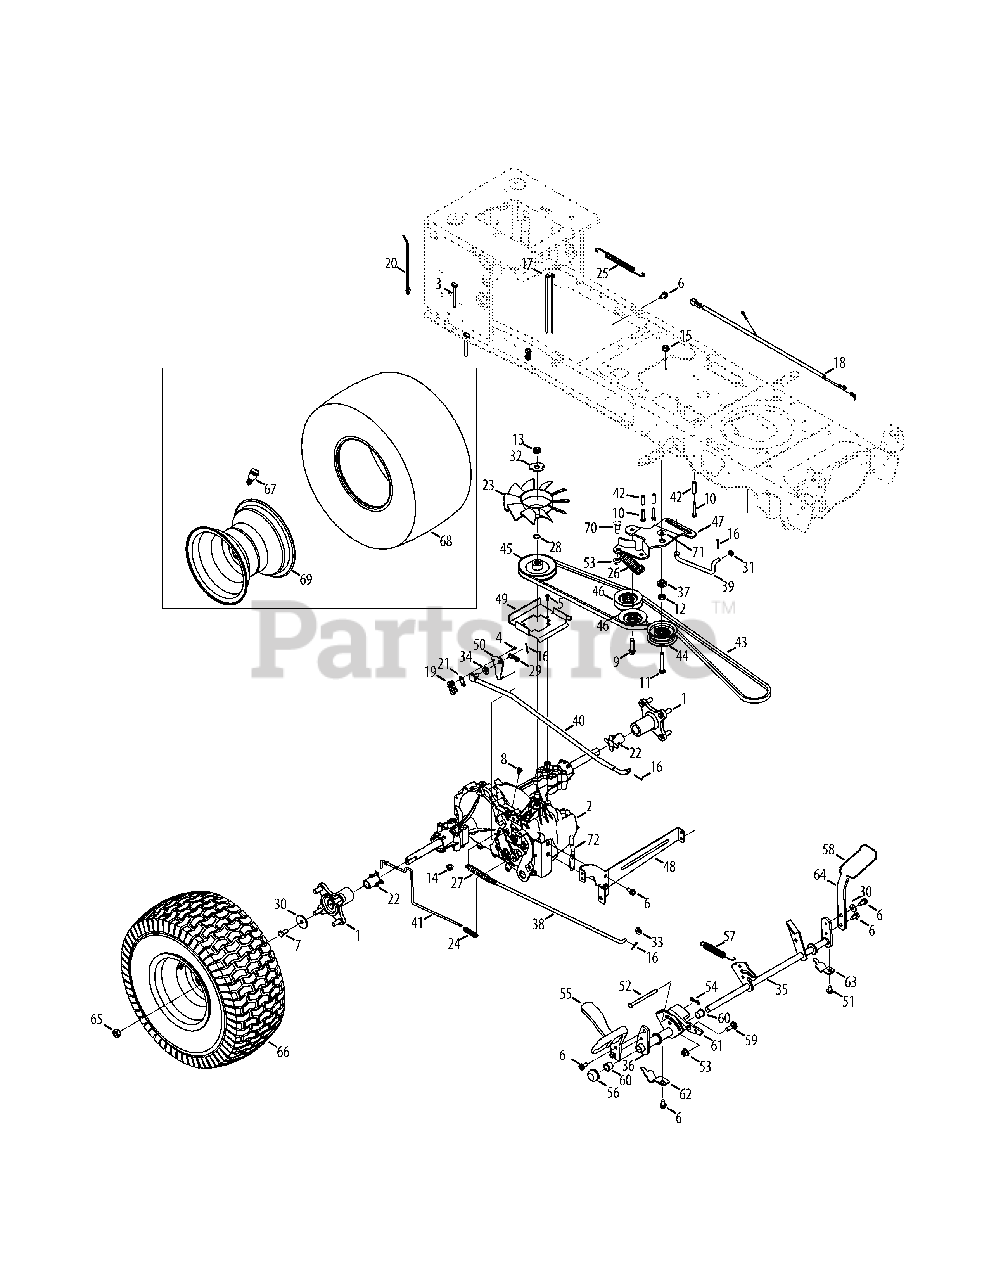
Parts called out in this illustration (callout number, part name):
1	Wheel Hub Assembly
2	Hydro Transmission
3	Hex Head Screw, 5/16-18:2.75
4	Screw, Indented Washer, #8-18:0.500
5	Screw, #10-16:0.500
6	Taptite Screw, 5/16-18:.750
7	Hex Head Screw, 5/16-24:.750
8	Taptite Screw, 1/4-20:0.375
9	Taptite Sems Screw, :3/8-16:1.500
10	Taptite Screw, 1/4-20:1.625
11	Hex Head Screw, 3/8-16:2.25
12	Jam Nut, 7/16-20
13	Jamlock Nut, 1/2-20
14	Flangelock Nut, 5/16-18
15	Flangelock Nut, 3/8-16
16	Cotter Pin, 3/32:1.0
17	Cable Tie. 3/16 x .05 x 7.4
18	Jumper Harness
19	Short Spring Switch
20	Push Mount Cable Tie 7.5 LG
21	Insulator Nut Plate
22	Sleeve, .765 ID x 1.500 LG
24	Extension Spring, .48 OD x 2.03
25	Extension Spring, .500 DIA x 12.6 LG
26	Extension Spring, 1.00 DIA x 4.75
27	Extension Spring, .59 OD x 4.00 LG
28	Wire Ring
29	Extension Spring, .375 OD x 1.44 LG
30	Bell Washer, .340 x .872 x .060
31	Flat Washer, .330 x .630 x .0635
32	Lock Washer
33	Flat Washer, .344 x .750 x .120
34	Flat Washer, .407 x .812 x .135
35	Brake Control Assembly
36	Hydro Pedal Bracket Assembly
37	Shoulder Spacer, 1.375 x .380 x .183
39	Foot pedal Bypass Transmission Rod
40	Hydro Control Rod
41	Hydro Bypass Rod
42	Spacer, 260 x .372 x 1.420 LG
43	V-Belt, 4L x 78.9 POLY
44	Flat Idler Pulley, 2.75 OD
45	Input Pulley, 4.13 DIA
46	V Idler Pulley, x 3.06
47	Center Idler Bracket
48	Hydro Mounting Bracket
49	Belt Disengage Support Bracket
50	Switch Actuator Bracket
51	Taptite Screw, 5/16-18:0.625
52	Clevis Pin, 5/16 x 3.985
53	Flangelock Nut, 3/8-16
54	Bow-Tie Cotter Pin
55	Control Pedal
57	Extension Spring, .63 DIA x 4.95 LG
58	Brake Pedal Pad
59	Shoulder Bolt, .500 x .270:3/8-16
60	Flange Bearing, .630 ID x .695 OD x .60
61	Cruise Latch
62	Pedal Support Bracket
63	Pedal Support Bracket, 5/8
66	Wheel Assembly
67	Tubeless Air Valve
69	Rim Assembly
70	Scr, Shldr, .50 x .685 3/8-16
71	Washer, Flat, .385 x 1.0 x .030
72	Belt Keeper Rod
